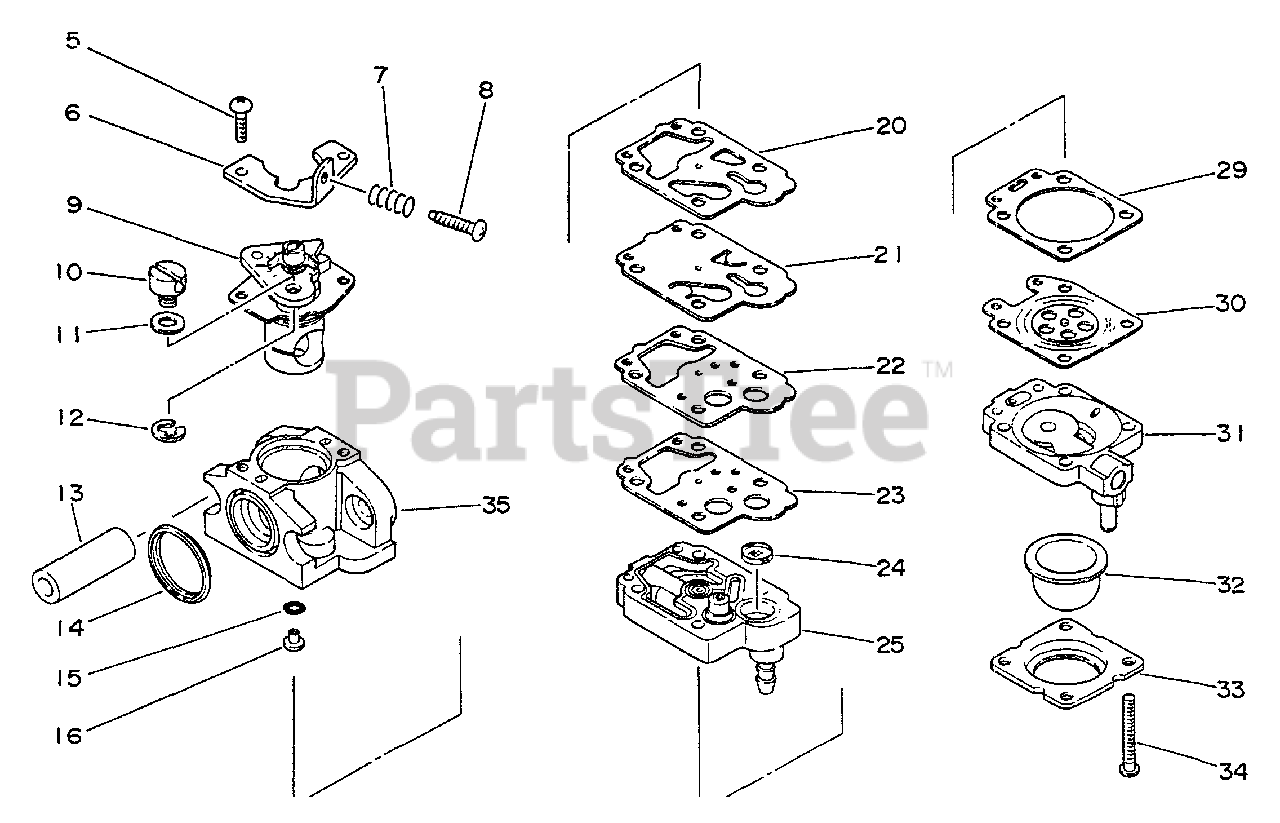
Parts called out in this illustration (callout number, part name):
6	BRACKET, THROTTLE CABLE
7	SPRING, IDLE ADJUST
8	SCREW, IDLE ADJUST
9	VALVE, THROTTLE
12	RING, RETAINING
13	SLEEVE, MOUNTING
14	SEAL
15	O-RING
16	JET
20	GASKET, PURGE
21	DIAPHRAGM, PURGE
22	PLATE, PUMP
23	GASKET, PLATE
24	STRAINER
25	BASE, PURGE
29	GASKET, METERING
30	DIAPHRAGM, METERING
31	BASE, PURGE
32	BULB, PURGE
33	RETAINER, PURGE BULB
35	BODY, CARBURETOR
